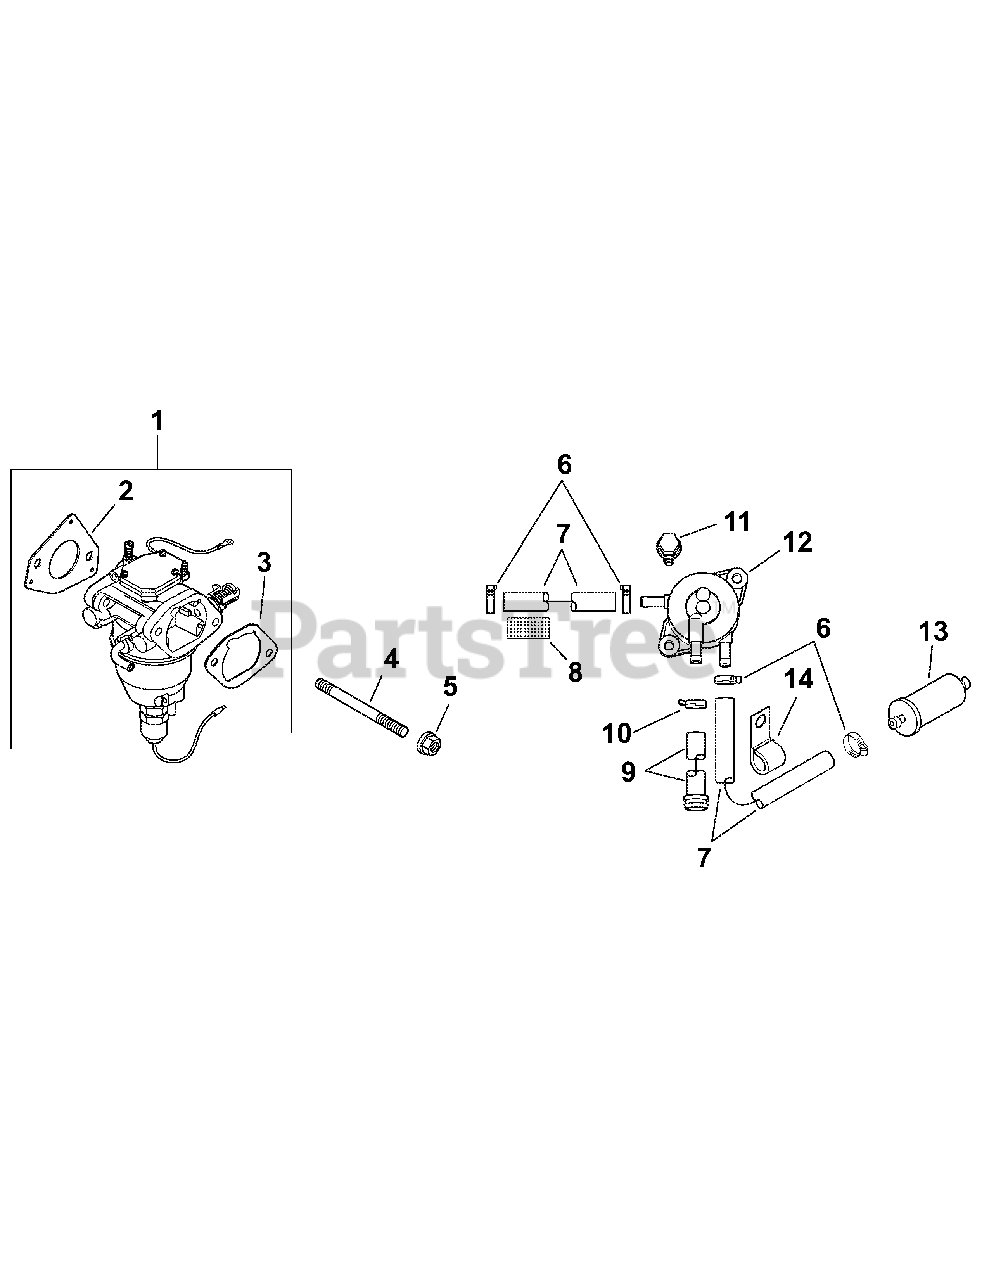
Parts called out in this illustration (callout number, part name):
1	KIT, CARBURETOR W/GASKETS
2	GASKET, CARBURETOR
3	GASKET, AIR CLEANER BASE
4	STUD, M6X1.0X106
5	NUT, FLG M6X1.0
6	CLAMP, SPRING HOSE 1/2"
7	LINE, FUEL
8	SLEEVE, ANTI ABRASION
9	KIT, FUEL PUMP HOSE W/CLAMP
11	SCREW, TAP M6X1.7X18
13	FILTER, FUEL
